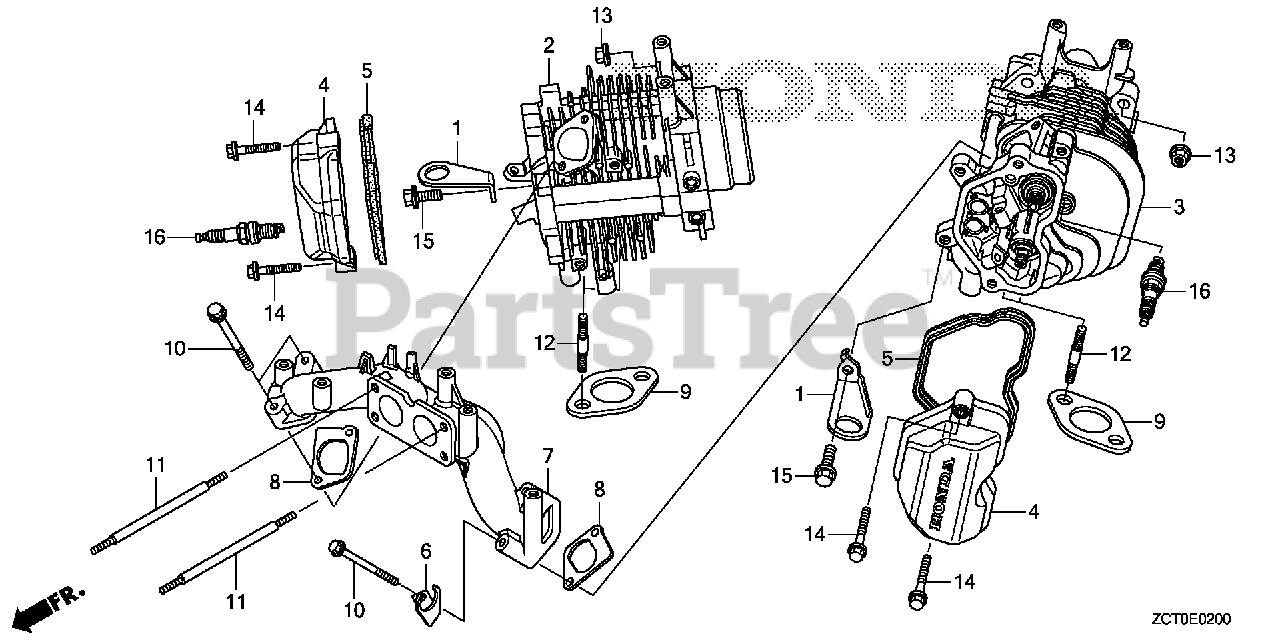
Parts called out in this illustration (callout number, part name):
1	HANGER, ENGINE
2	CYLINDER HEAD (#1)
3	CYLINDER HEAD (#2)
4	COVER, CYLINDER HEAD
5	GASKET, HEAD COVER
6	STAY, FUEL TUBE GROMMET
7	MANIFOLD, IN.
8	GASKET, IN. MANIFOLD
9	GASKET, EX. PIPE
10	BOLT, FLANGE (8X55)
11	BOLT, STUD (6X106)
12	BOLT, STUD (8X22)
13	NUT, FLANGE (10MM)
14	BOLT, FLANGE (6X30)
15	BOLT, FLANGE (8X16)
16	SPARK PLUG (ZFR5F)
